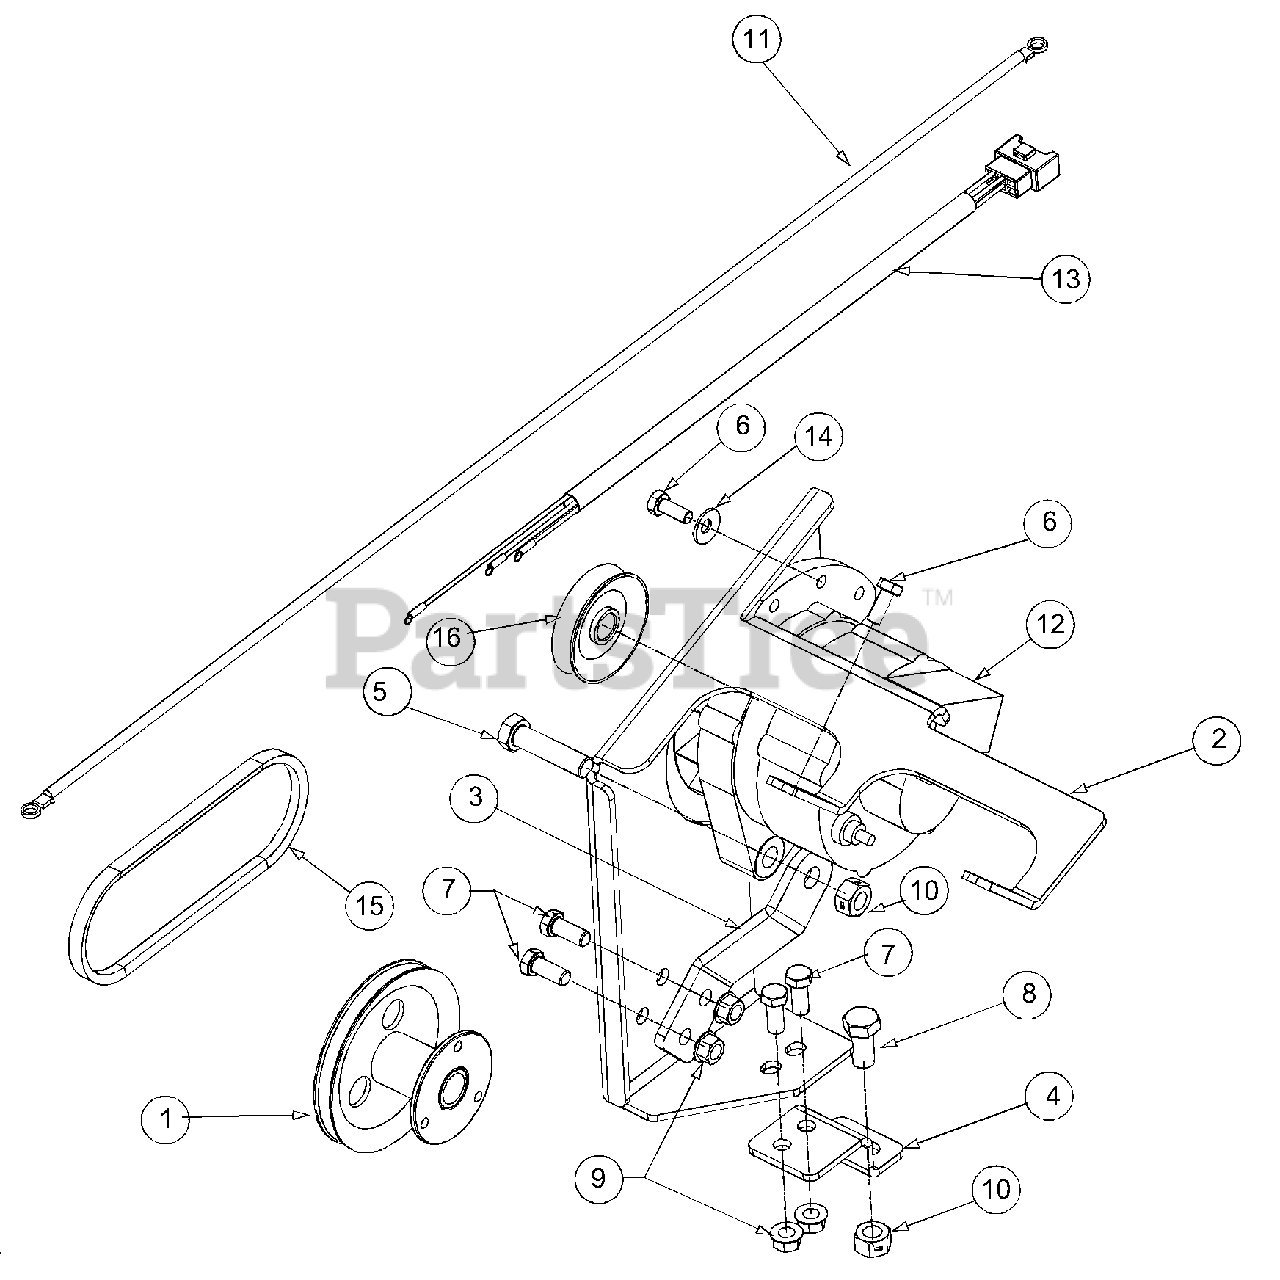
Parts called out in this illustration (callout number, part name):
6	Screw, M8- 1.25 - 20
7	Hex Screw, 3/8-16 x .880, Gr5
8	Hex Screw, 1/2-13 GR8
9	Nut, Flange Lock, 3/8-16
10	Nut, Hex Lock, 1/2-13
11	Harness, Aux, Alternator
12	Alternator, Aux 65 Amp
13	Harness, Alternator Regulator
14	Washer, Bell, .340 x .872 x .060
15	V-Belt 3/8 x 35.68 LG
16	Pulley, 2.65 OD
